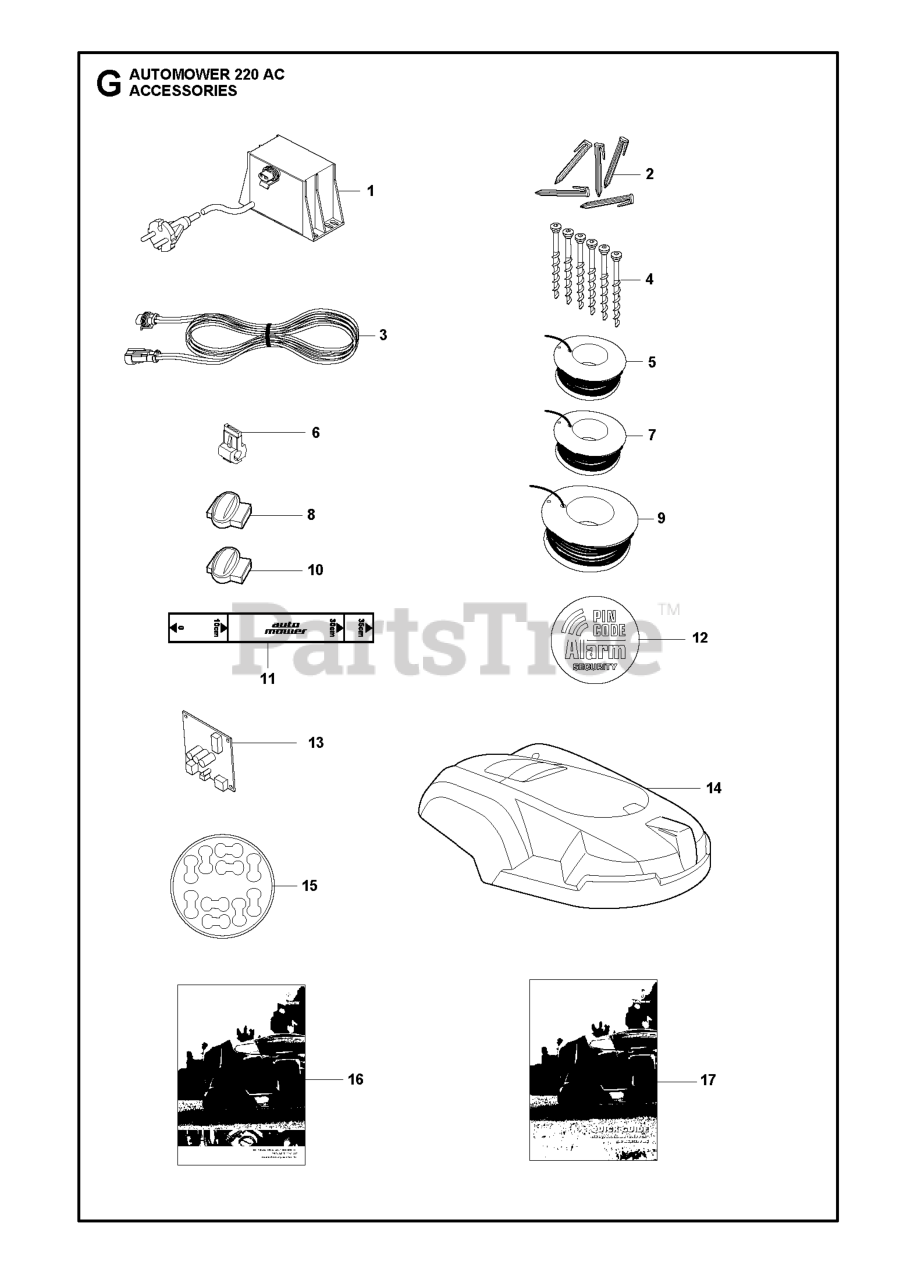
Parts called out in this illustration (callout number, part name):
1	TRANSFORMER/US
1	TRANSFORMER
2	STAPLE 100 PCS, BLISTER
2	STAPLE 100 PCS
3	LOW VOLT WIRING
4	SCREW 3 PCS, BLISTER PACK
4	SCREW KIT CS
5	WIRE BOUNDARY 150M
5	WIRE 150M, BLISTER
6	BRAKER
6	CONNECTOR 5 PCS, BLISTER
7	WIRE 250M
8	SPLICE KIT
8	COUPLER SPLICER, 5 PCS,
9	WIRE 500M
10	COUPLER SPLICER, 100 PCS
11	RULER / CENTIMETERS
12	LABEL SECURITY
13	CIRCUIT BOARD ASSY PCBA GEN BO
14	BODY WATER, DARK BLUE
14	BODY AIR, CREAM WHITE
14	BODY EARTH, BROWN
14	BODY FIRE, ORANGE
15	STICKER CABLE MARKERS KIT 10PC
